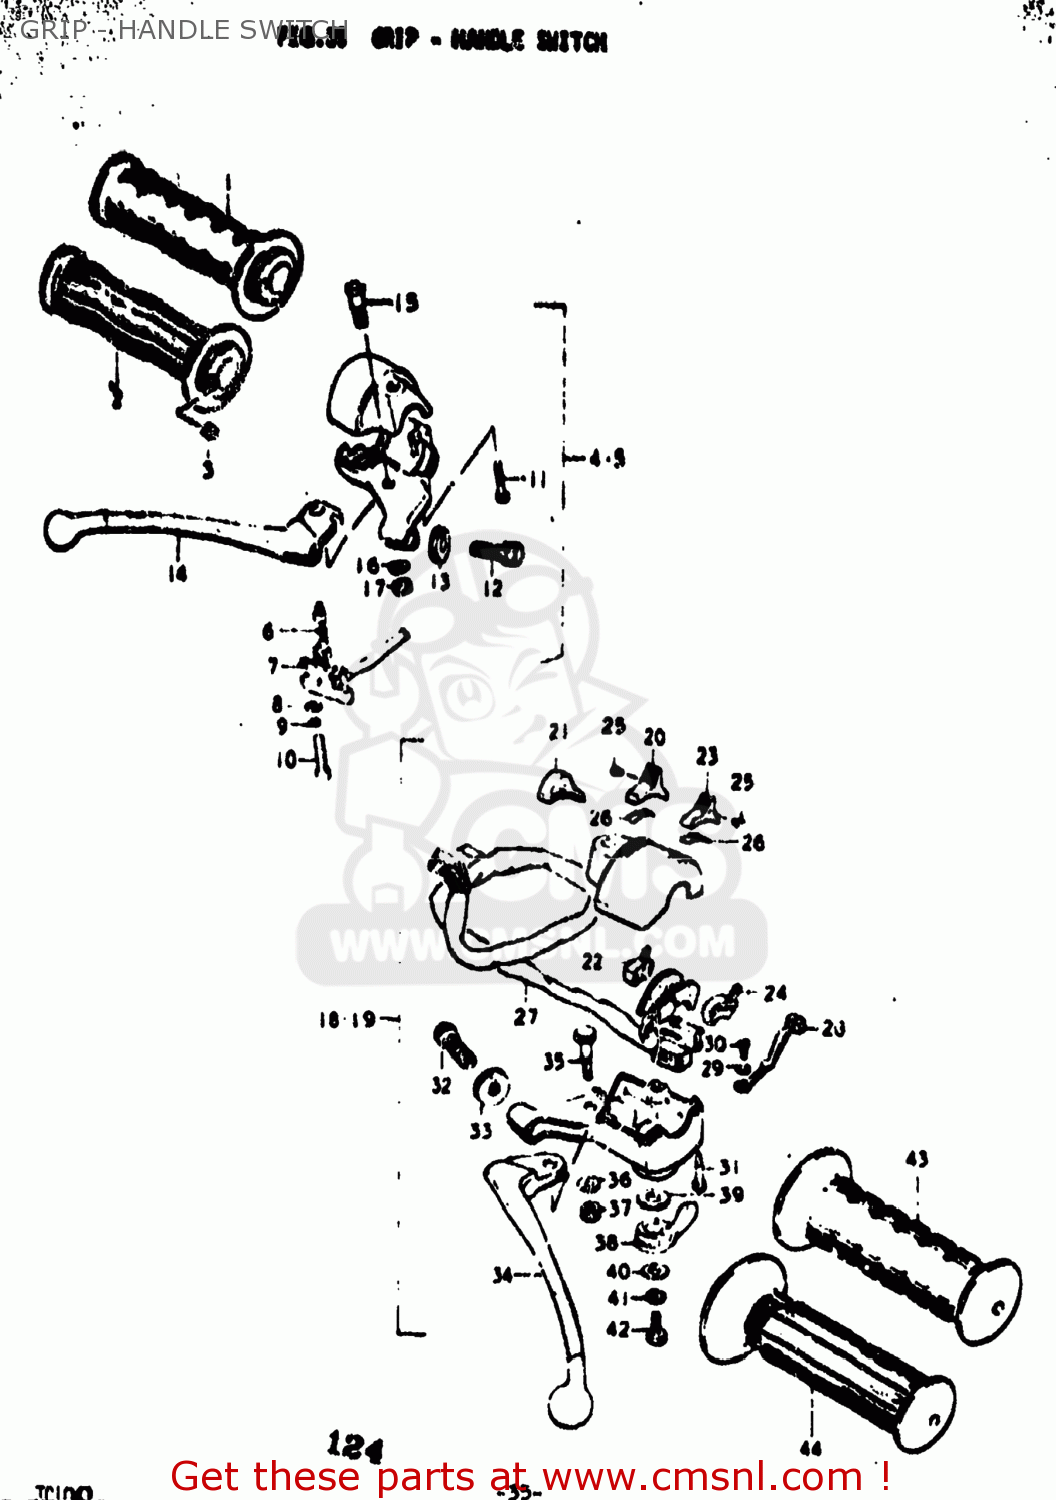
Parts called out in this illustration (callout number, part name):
1	GRIP,THROTTLE
2	GRIP,THROTTLE
3	PIECE,THROTTLE END
4	LEVER ASSEMBLY
5	LEVER/SWITCH ASSEMBLY,BRAKE
6	SPRING
7	SWITCH ASSEMBLY
8	WASHER
9	LOCK WASHER
10	SCREW
11	SCREW
12	ADJUSTER,CABLE
13	NUT,CABLE ADJUSTER
14	LEVER ASSEMBLY,ADJUST
15	BOLT
16	LOCK WASHER
17	NUT
18	LEVER ASSEMBLY
19	LEVER ASSEMBLY
20	KNOB,HANDLE SWITCH
22	SLIDING BLOCK, LIGHTING
23	KNOB,HANDLE SWITCH
24	SLIDING BLOCK, DIMMER
25	SCREW
26	PLATE,SWITCH KNOB
27	WIRING HARNESS
28	KNOB,TURN SIGNAL SWITCH
30	SCREW
31	SCREW
32	ADJUSTER,CABLE
33	NUT,CABLE ADJUSTER
34	LEVER,CLUTCH
35	BOLT
36	LOCK WASHER
37	NUT
38	LEVER,STARTER
39	WASHER,ADJUSTER
40	WASHER,STARTER LEVER
41	LOCK WASHER
42	BOLT
43	GRIP
44	GRIP,LEFT
